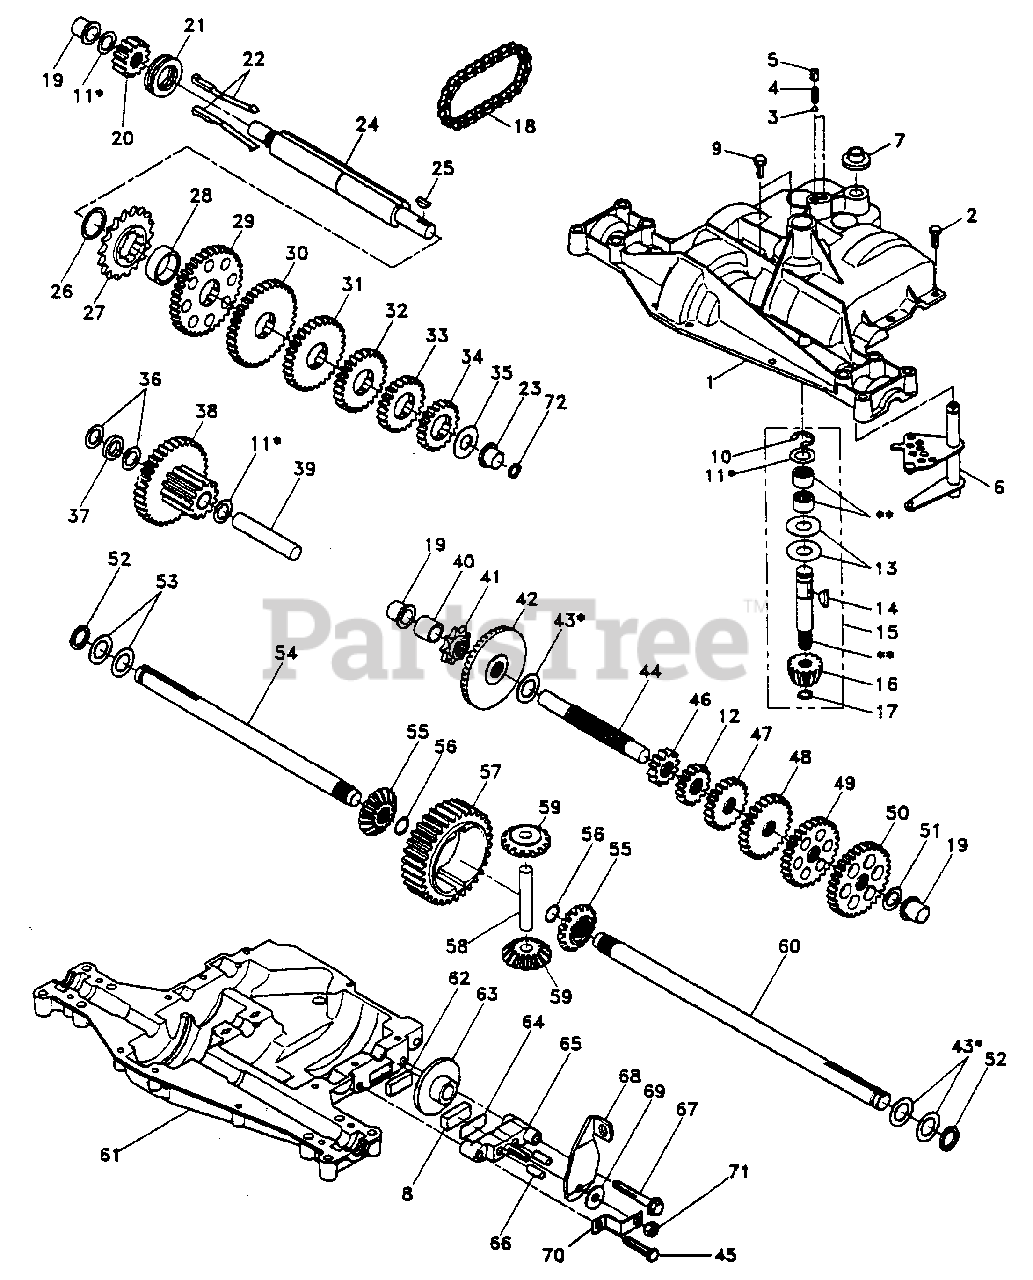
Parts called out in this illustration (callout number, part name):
1	Housing, Upper (AYP part number)
2	Screw, Self-Tapping, Large 1/4-20 x .734 (AYP part number)
3	Ball, Detent (AYP part number)
4	Spring, Detent (AYP part number)
5	Screw, Set (AYP part number)
6	Kit, Shifter Assembly (AYP part number)
7	Boot, Shifter (AYP part number)
8	Puck, Friction (AYP part number)
9	Screw, Self-Tapping, with Sealer (AYP part number)
10	Ring, Retaining (AYP part number)
11	Assembly, Kit, Shim .625 Shaft (AYP part number)
12	Gear, Spur, 15 Teeth (AYP part number)
13	Washer, Plain .632 x 1.38 x .046 (AYP part number)
14	Key, Woodruff, #9 (AYP part number)
15	Assembly, Kit, Input Shaft (AYP part number)
16	Pinion, Bevel, 14 Teeth (AYP part number)
17	Ring, Retaining (AYP part number)
18	Chain, 24 Pitches (AYP part number)
19	Bearing, Flange (AYP part number)
20	Gear, Spur, 14 Teeth (AYP part number)
21	Collar, Clutch (AYP part number)
22	Assembly, Kit, Clutch Keys (AYP part number)
23	Bearing, Flange (AYP part number)
24	Shaft, Intermediate (AYP part number)
25	Key, Woodruff, #61 (AYP part number)
26	Ring, Retaining (AYP part number)
27	Sprocket, 18 Teeth (AYP part number)
28	Spacer (AYP part number)
29	Gear, Spur, 37 Teeth (AYP part number)
30	Gear, Spur, 35 Teeth (AYP part number)
31	Gear, Spur, 30 Teeth (AYP part number)
32	Gear, Spur, 25 Teeth (AYP part number)
33	Gear, Spur, 22 Teeth (AYP part number)
34	Gear, Spur, 19 Teeth (AYP part number)
35	Washer, Plain .640 x 1.37 x .061 (AYP part number)
36	Washer, Plain .632 x 1.00 x .026 (AYP part number)
37	Spacer .630 x 1.00 x .169 (AYP part number)
38	Assembly, Gear, Combination of 12 Teeth and 35 Teeth (AYP part number)
39	Shaft, Idler (AYP part number)
40	Spacer .635 x .875 x .755 (AYP part number)
41	Sprocket, 9 Teeth (AYP part number)
42	Gear, Bevel, 42 Teeth (AYP part number)
43	Assembly, Kit, Shim .750 Shaft (AYP part number)
44	Shaft, Drive (AYP part number)
45	Screw, Self-Tapping, Large 5/16-18 x 1.44 (AYP part number)
46	Gear, Spur, 12 Teeth (AYP part number)
47	Gear, Spur, 20 Teeth (AYP part number)
48	Gear, Spur, 25 Teeth (AYP part number)
49	Gear, Spur, 28 Teeth (AYP part number)
50	Gear, Spur, 31 Teeth (AYP part number)
51	Washer, Plain .632 x 1.00 x .060 (AYP part number)
52	Washer, Neoprene (AYP part number)
53	Washer, Plain .758 x 1.25 x .031 (AYP part number)
54	Axle, L.H. (AYP part number)
55	Gear, Miter, 15 Teeth (AYP part number)
56	Ring, Retaining (AYP part number)
57	Gear, Spur, 32 Teeth (AYP part number)
58	Shaft, Cross (AYP part number)
59	Gear, Miter, 15 Teeth (AYP part number)
60	Axle, R.H. (AYP part number)
61	Housing, Lower (AYP part number)
62	Puck, Friction (AYP part number)
63	Disc, Brake (AYP part number)
64	Spacer (AYP part number)
65	Jaw, Brake (AYP part number)
66	Pin, Dowel (AYP part number)
67	Screw, Self-Tapping, Large 5/16-18 x 2.25 (AYP part number)
68	Lever, Actuating (AYP part number)
69	Washer, Plain .321 x 1.00 x .055 (AYP part number)
70	Bracket, Anti-Rotation (AYP part number)
71	Locknut 5/16-24 (AYP part number)
72	Seal, Oil (AYP part number)
73	Grease (AYP part number)
